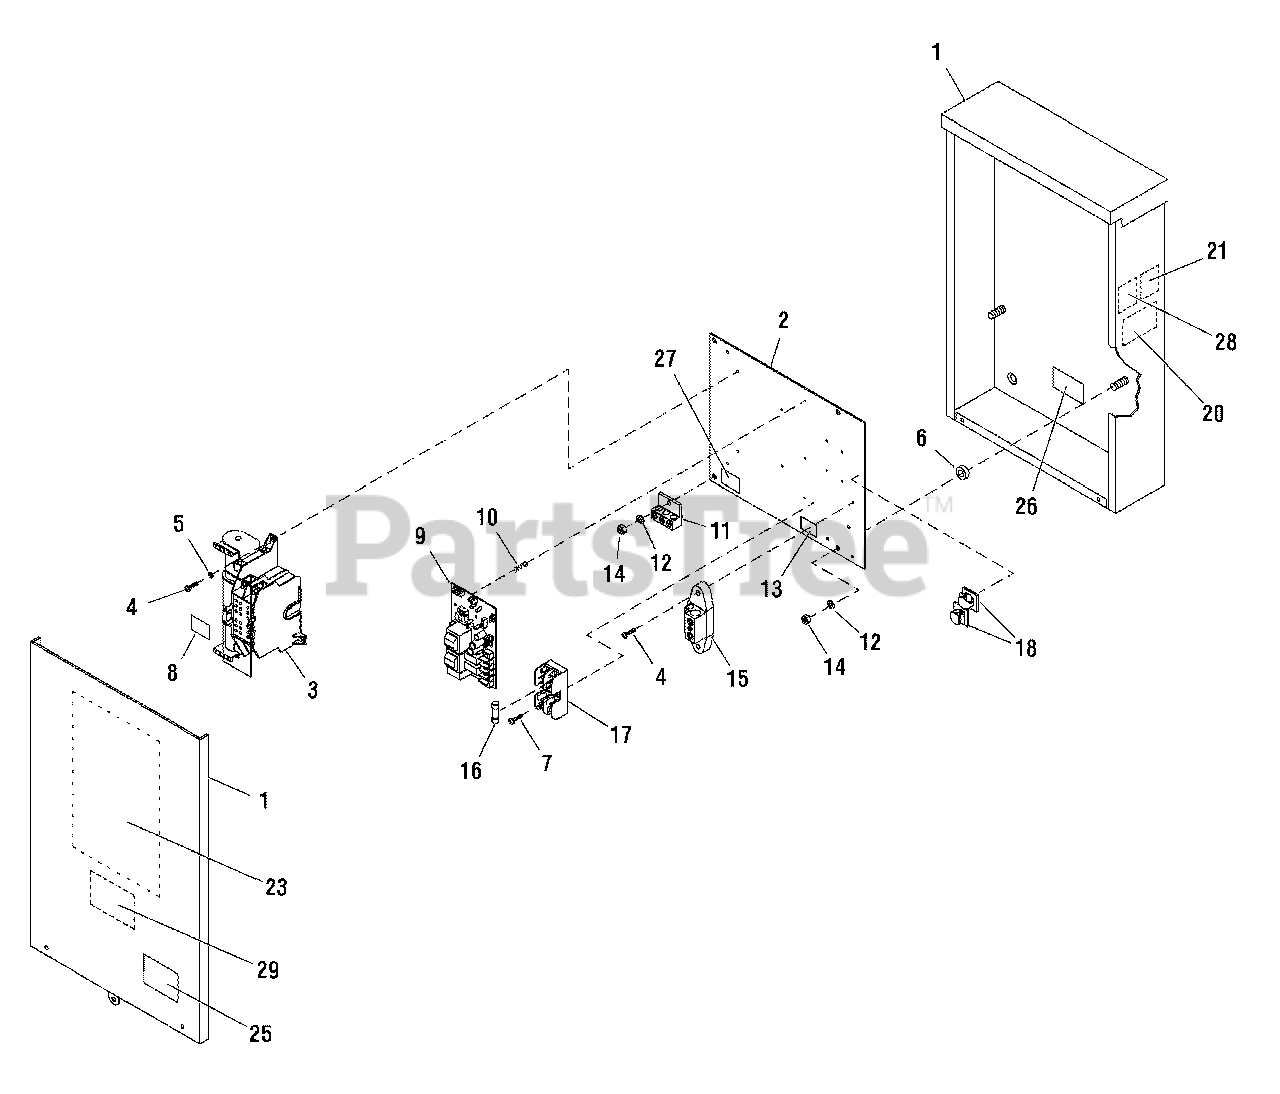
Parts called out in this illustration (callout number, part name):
1	ENCLOSURE
2	BACK PANEL
3	SWITCH, Transfer
4	* SCREW, Phillips Head, #10 - 32 x 1/2
5	* WASHER-EXT. #10
6	SPACER
7	* SCREW, Phillips Head, #6-32 x 3/8
8	DECAL
11	GROUND LUG
12	* WASHER, Lock, 1/4
13	DECAL
14	* NUT, 1/4-20
16	FUSE
28	DECAL
